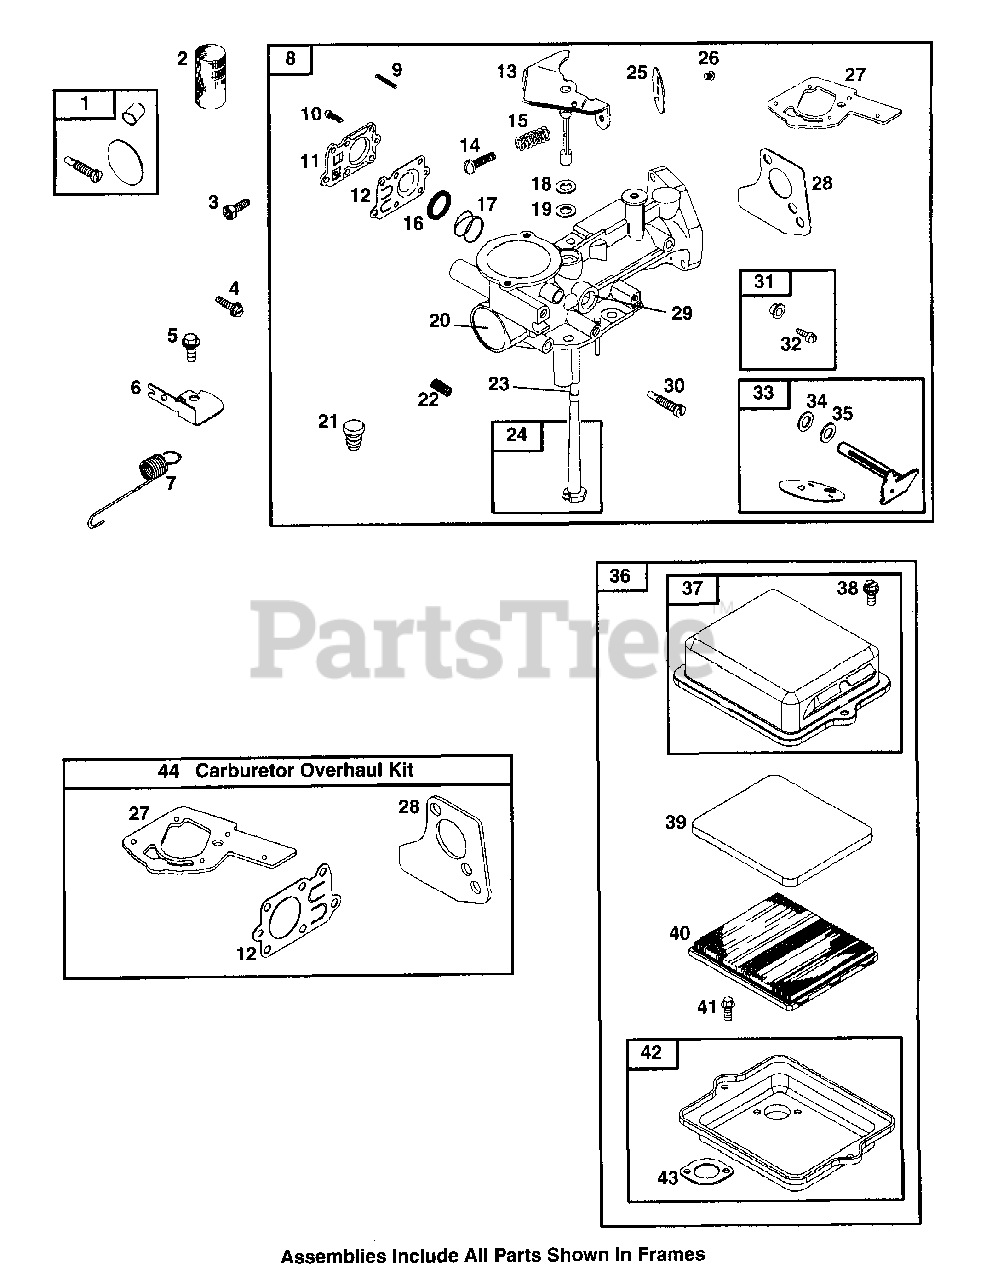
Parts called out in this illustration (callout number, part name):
1	Pilot Jet (High Altitude)
2	Carburetor Screen
3	Screw (Carburetor)
4	Screw (Casing Clamp)
5	Screw (Spring Anchor)
6	Spring Anchor
7	Governed Idle Spring
8	Carburetor
9	Locating Pin
10	Screw (Diaphragm Cover)
11	Diaphragm Cover
12	Carburetor Diaphragm
13	Throttle Shaft
14	Screw (Idle Speed Adjustment)
15	Friction Spring
16	Spring Cap
17	Pump Diaphragm Spring
18	Throttle Shaft Seal
19	Throttle Shaft Seal
20	Welch Plug
21	Carburetor Plug
22	Detent Spring (Choke)
24	Pickup Tube
25	Throttle Valve
26	Screw (Throttle Valve)
27	Fuel Tank Gasket
28	Intake Gasket
29	Welch Plug
31	Collar/Screw Kit
32	Screw (Collar/Screw Kit)
33	Choke Shaft Kit
35	Washer (Choke Shaft)
36	Air Cleaner
37	Air Cleaner Cover
38	Screw (Air Cleaner Cover)
39	Pre-Cleaner Filter
40	Air Cleaner Cartridge Filter
41	Screw (Air Cleaner Base)
42	Air Cleaner Base
43	Air Cleaner Gasket
44	Carburetor Kit
